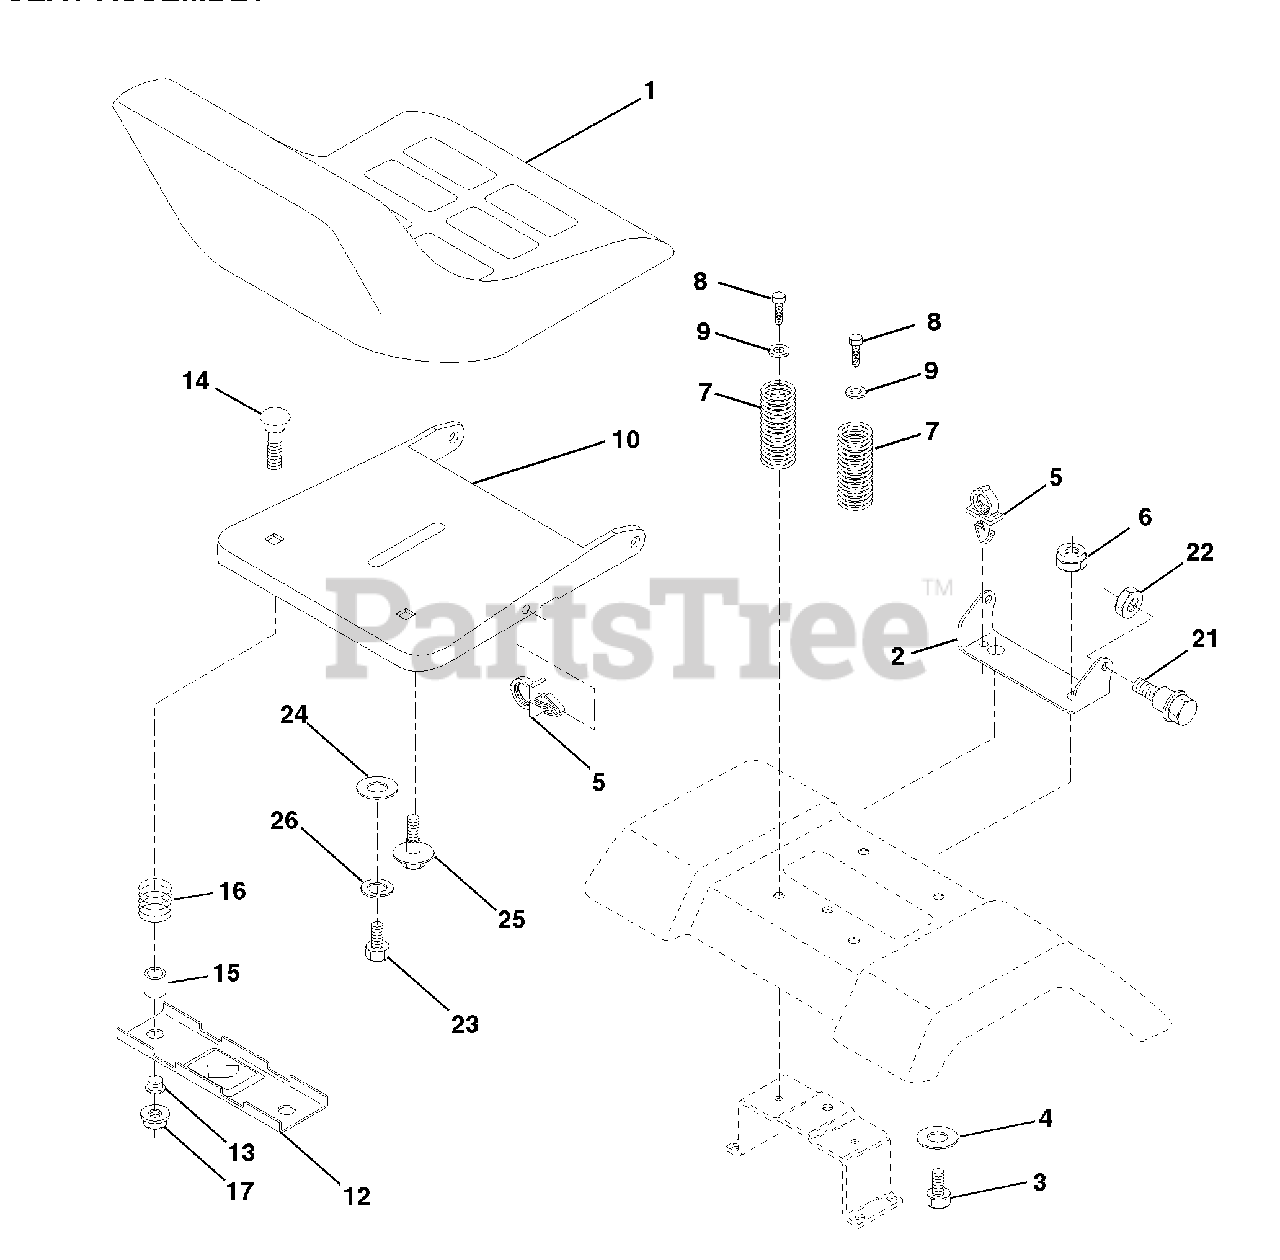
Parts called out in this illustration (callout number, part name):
1	Seat
2	Bracket Pivot Seat 8 720
3	Bolt Fin Hex 3/8-16unc X 1
4	Washer 13/32 X 1 X 10 Ga
5	Clip Push-In
6	Nut Hex w/Ins. 3/8-16 Unc
7	Spring Seat Cprsn 2 250 Blk Zi
8	Screw Thdrol 3/8-16 X 1 Ty-tt
9	Washer 13/32 X 1 X 14 Ga.
10	Pan Seat
12	Bracket Mounting Switch
13	Bushing Snap Blk Nyl 50 Id
14	Bolt Rdhd Sqnk 1/4-20x1-1/2
15	Spacer Split 28x 96 Yel Zinc
16	Spring Cprsn 1 27 Blk Pnt
17	Nut Lock 1/4 Lge Flg Gr 5 Zinc
21	Bolt Shoulder 5/16-18 Unc
22	Nut Hex Lock W/Ins 5/16-18
23	Bolt, Hex Head, Fin 1/2-13 x 7/8 Grade 5
24	Washer 17/32 X 1-3/16 X 12 Ga.
25	Bolt Shoulder 5/16-18 X 62
26	Washer Lock
